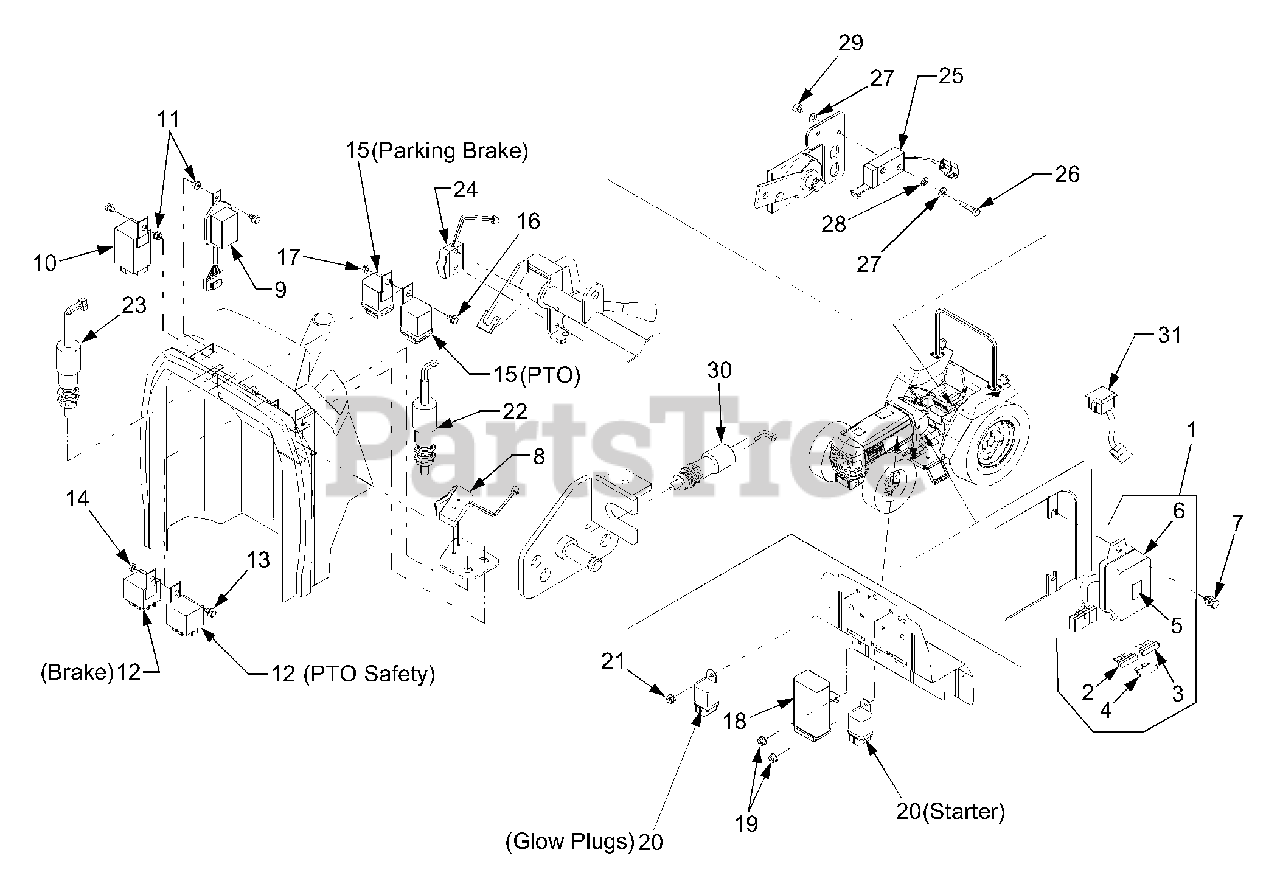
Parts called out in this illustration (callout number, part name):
1	Fuse Box Ass'y
2	Fuse (25a)
3	Fuse (20a)
8	Switch, Micro
9	Relay, Timer
10	Unit, Flasher
18	Controller, Preheater
20	Relay
22	Switch, Safety Starter
23	Stop Switch Ass'y
24	Switch, Micro
25	Switch, Micro
27	Washer, Plain
28	Washer, Spring
30	Safety Starter Ass'y
